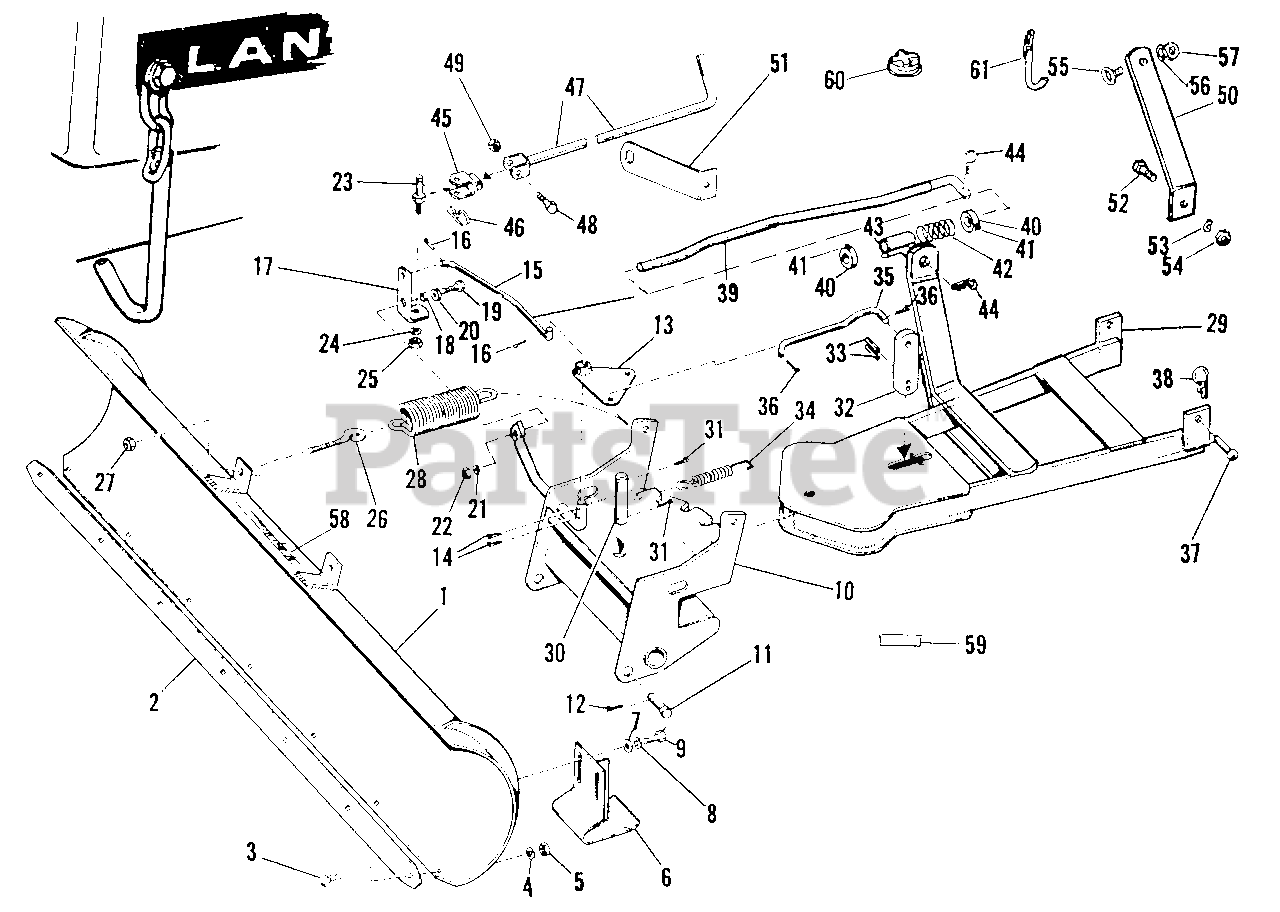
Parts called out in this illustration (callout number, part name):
1	Blade Assy.
3	Carriage Bolt, 3/8"-16 x 1"
4	Lock Washer, 3/8"
5	Hex Nut, Full 3/8"-16
6	Shoe Assy.
7	Flat Washer, 3/8"
8	Lock Washer, 3/8"
9	Hex. Cap Screw, 3/8"-16 x 3/4"
10	Pivot Frame Assy.
12	Cotter Pin, 1/8" x 1"
13	Pivot Plate Assy.
14	Cotter Pin, 1/8" x 1"
16	Cotter Pin, 3/32" x 5/8"
17	Pivot Arm
19	Hex Capscrew, 5/16"-18 x 1"
20	Plain Washer, 5/16"
21	Lock Washer, 5/16"
22	Hex Nut, Full, 5/16"-18
24	Lock Washer, 5/16"
25	Hex Nut, Full, 5/16"-18
27	Hex Nut, Full, 5/16-18
29	Push Bar Assy.
30	Pivot Pin
31	Cotter Pin, 3/16" x 1-1/4"
33	Roll Pin, 7/32" x 1"
34	Latch Spring
36	Cotter Pin, 3/32" x 5/8"
37	(Hitch) Pin
38	Hairpin Clip
39	Front Lift Rod
40	Collar
41	Set Screw 5/16"-18 x 3/8"
44	Hairpin Clip
45	Fork Assy.
46	Hairpin Clip
47	Handle Assy.
48	Hex Capscrew, 5/16"-18 x 1-1/2"
49	Full Lock Hex Nut 5/16"-18
50	Bracket (For 1971 Tractors Only)
52	Hex Capscrew, 3/8"-16 x 3/4"
53	Lock Washer, 3/8"
54	Hex Nut, Full 3/8"-16
56	Lock Washer, 1/4"
57	Hex Nut, Full, 1/4-20
58	Film, Simplicity
59	Model No. Plate
60	Fuel Tank Cap (Winterized)
61	Transport Chain Assy.
